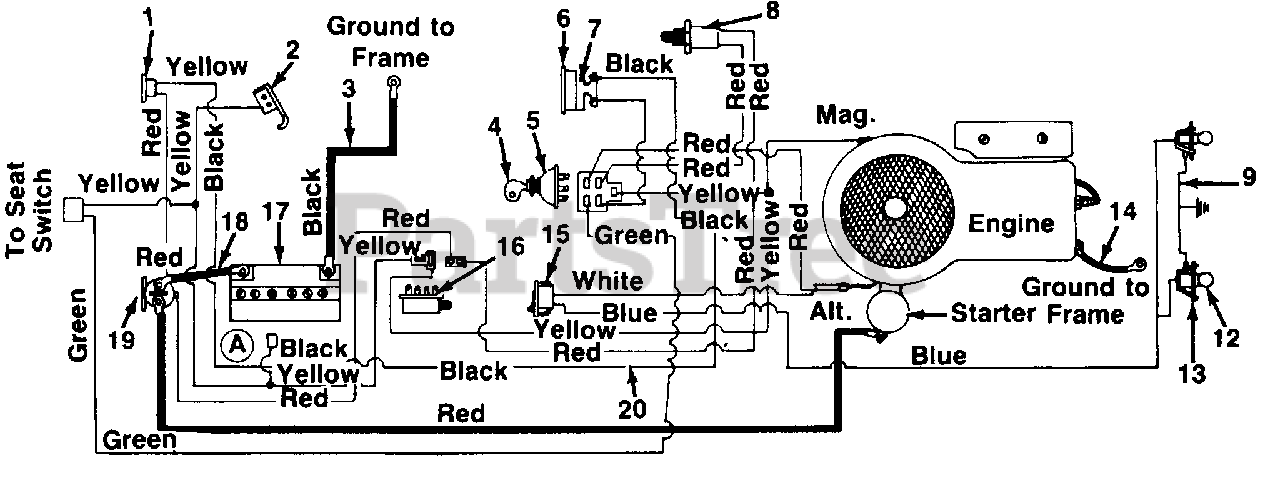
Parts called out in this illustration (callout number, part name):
1	Circuit Breaker
2	Spring-Switch-Reverse
3	Ground Wire 9.0" Lg.
4	Ignition Key
5	Ignition Switch
6	Ammeter
7	Foam Strip
8	Safety Switch
9	Ground Wire
12	Lamp
13	Socket
14	Ground Wire 7.25" Lg.
15	Light Switch
16	Safety Switch
17	Battery
18	Electric Wire w/Boot
19	Solenoid
20	Wire Harness
